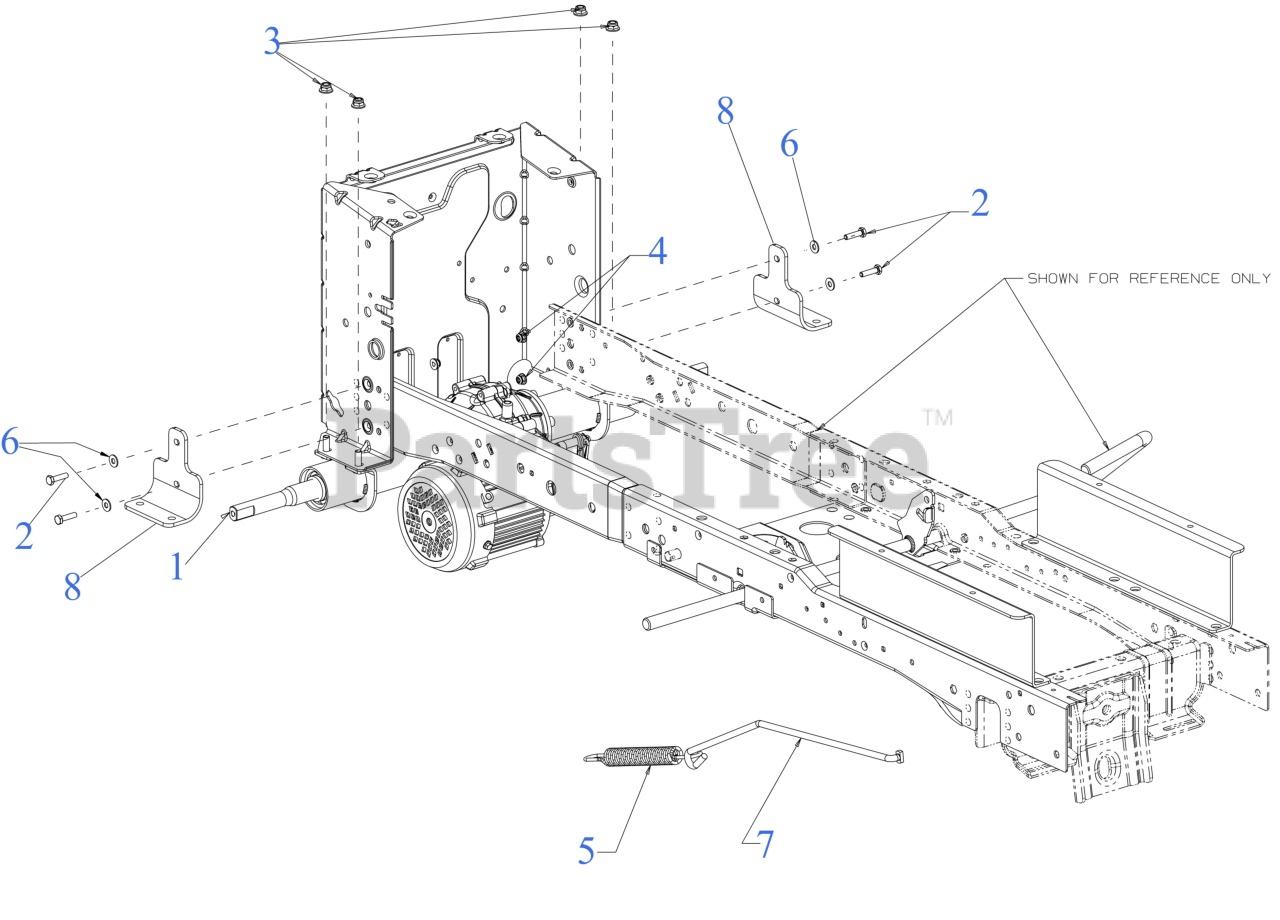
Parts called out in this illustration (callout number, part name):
1	TRANSMISSION
2	SCREW 1/4-20 X1.00 GR5
3	FLANGE LOCK NUT 5/16-18
4	FLANGE LOCK NUT
5	EXTENSION SPRING 0.90 DIA x 8.14
6	FLAT WASHER
8	TRANSMISSION BRACKET
